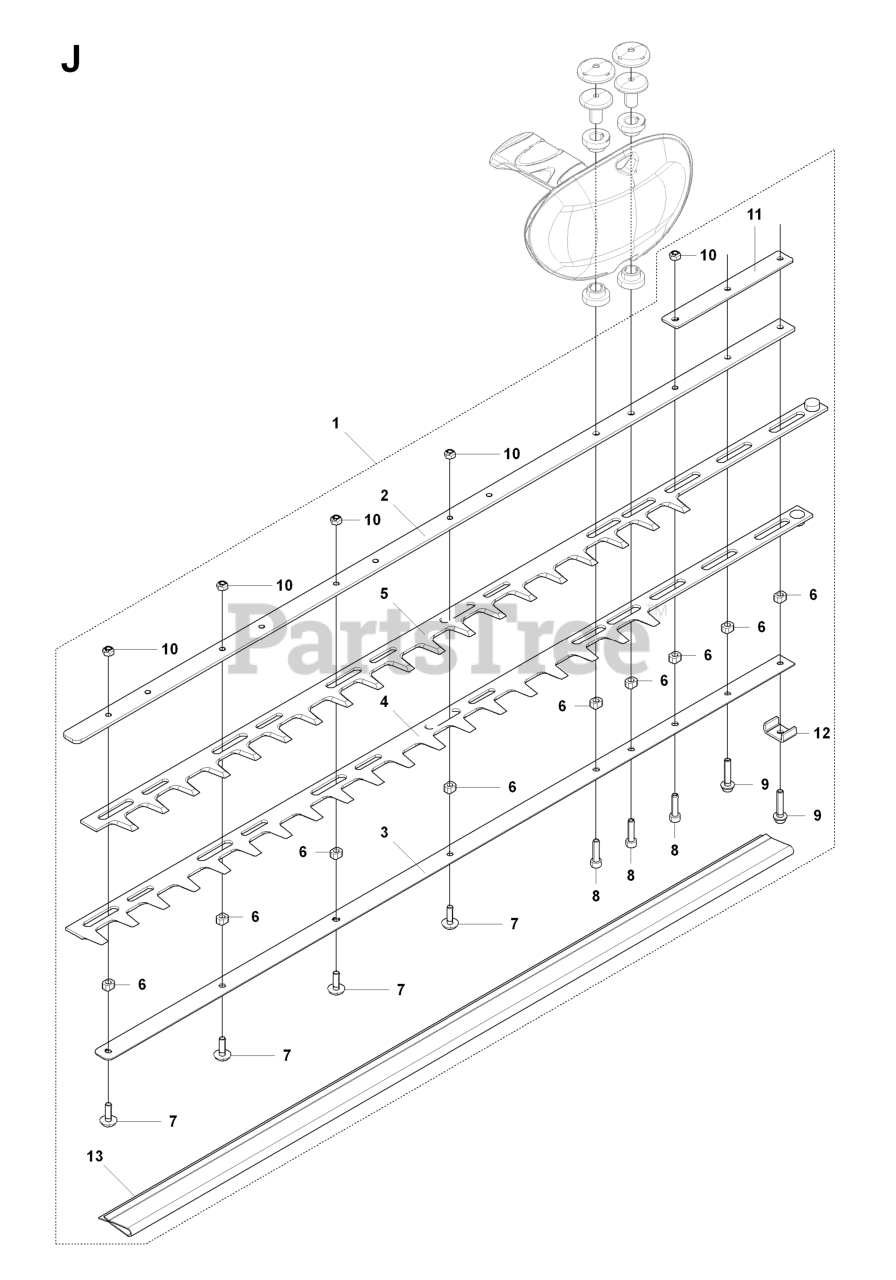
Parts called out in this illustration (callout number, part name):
1	BLADE ASSY
2	PLATE UPPER
3	PLATE LOWER
4	BLADE LOWER
5	BLADE UPPER
13	COVER
